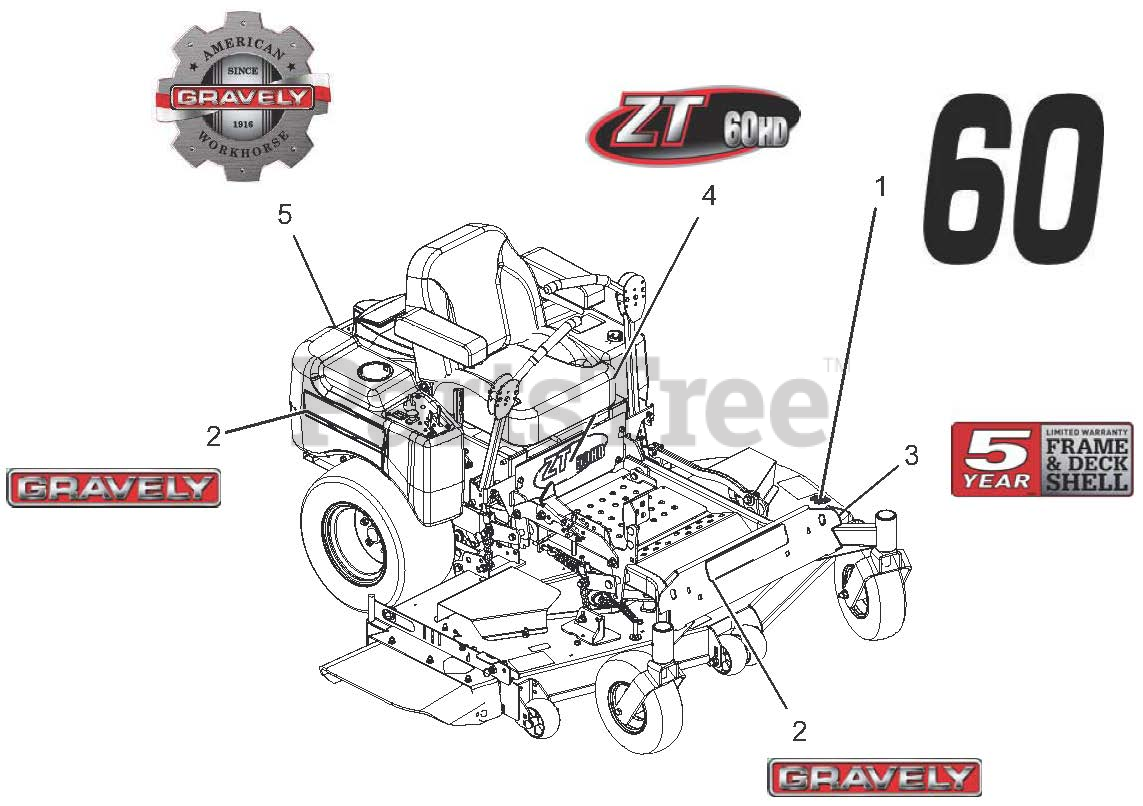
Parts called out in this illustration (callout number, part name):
1	DECAK, 60"
2	DECAL, FUEL TANK - GRAVELY
3	DECAL, DECK WARRANTY - FAB GRAVELY
4	DECAL, 60HD
5	DECAL, GRAVELY HERITAGE - SMALL
